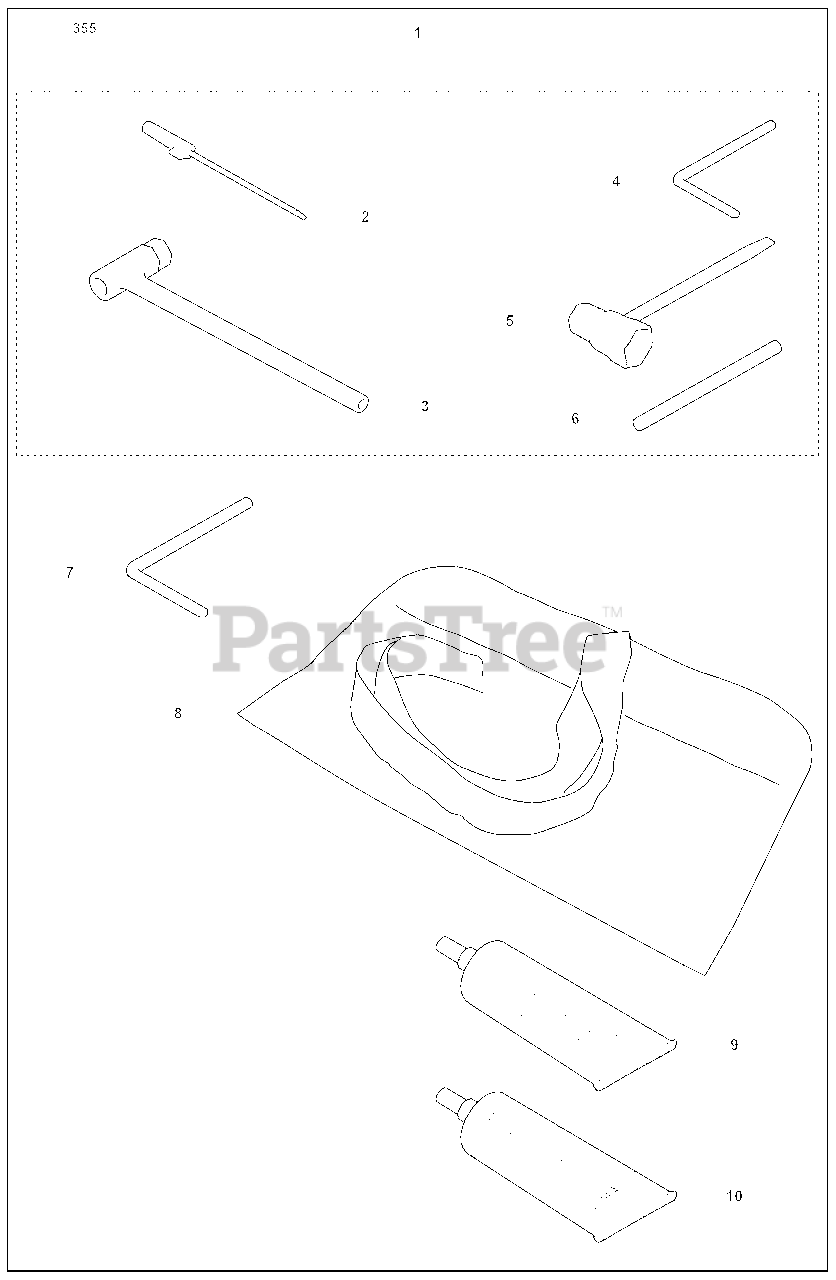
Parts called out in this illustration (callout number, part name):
1	RP ACCESSORY BAG
1	ACCESORY BAG
2	SCREWDRIVER
4	L-KEY WRENCH
5	COMBI TOOL
6	LOCKING PIN
7	KEY
9	BEVEL GEAR GREASE
